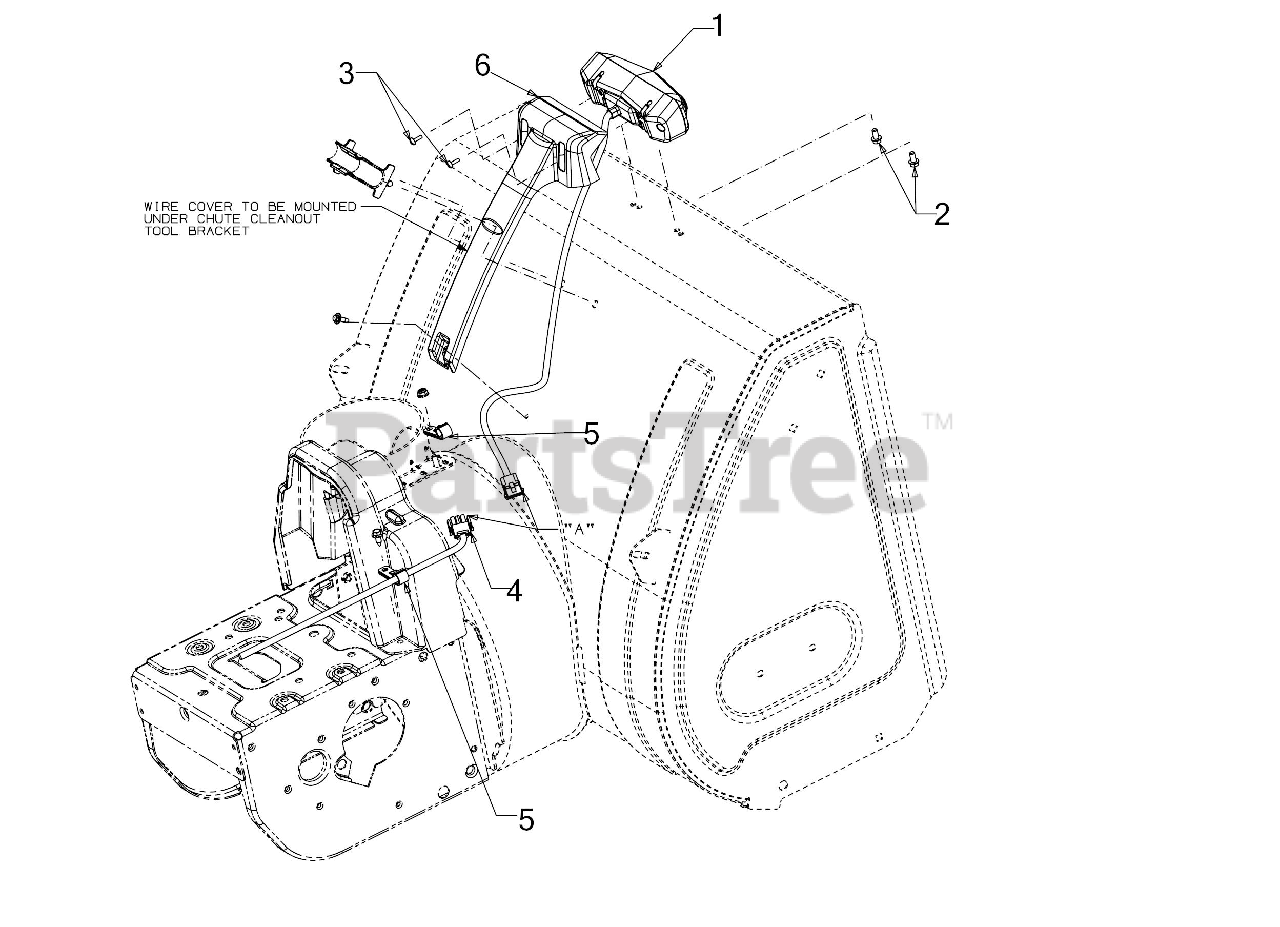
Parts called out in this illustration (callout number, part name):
1	LED LIGHT BAR HEADLIGHT ASSEMBLY
2	HEX SCREW 1/4-15 x .50
3	SCREW 8/16 x .500
4	LED HEADLIGHT HARNESS
5	HEADLIGHT HARNESS CLAMP
6	LED LIGHT BAR COVER
